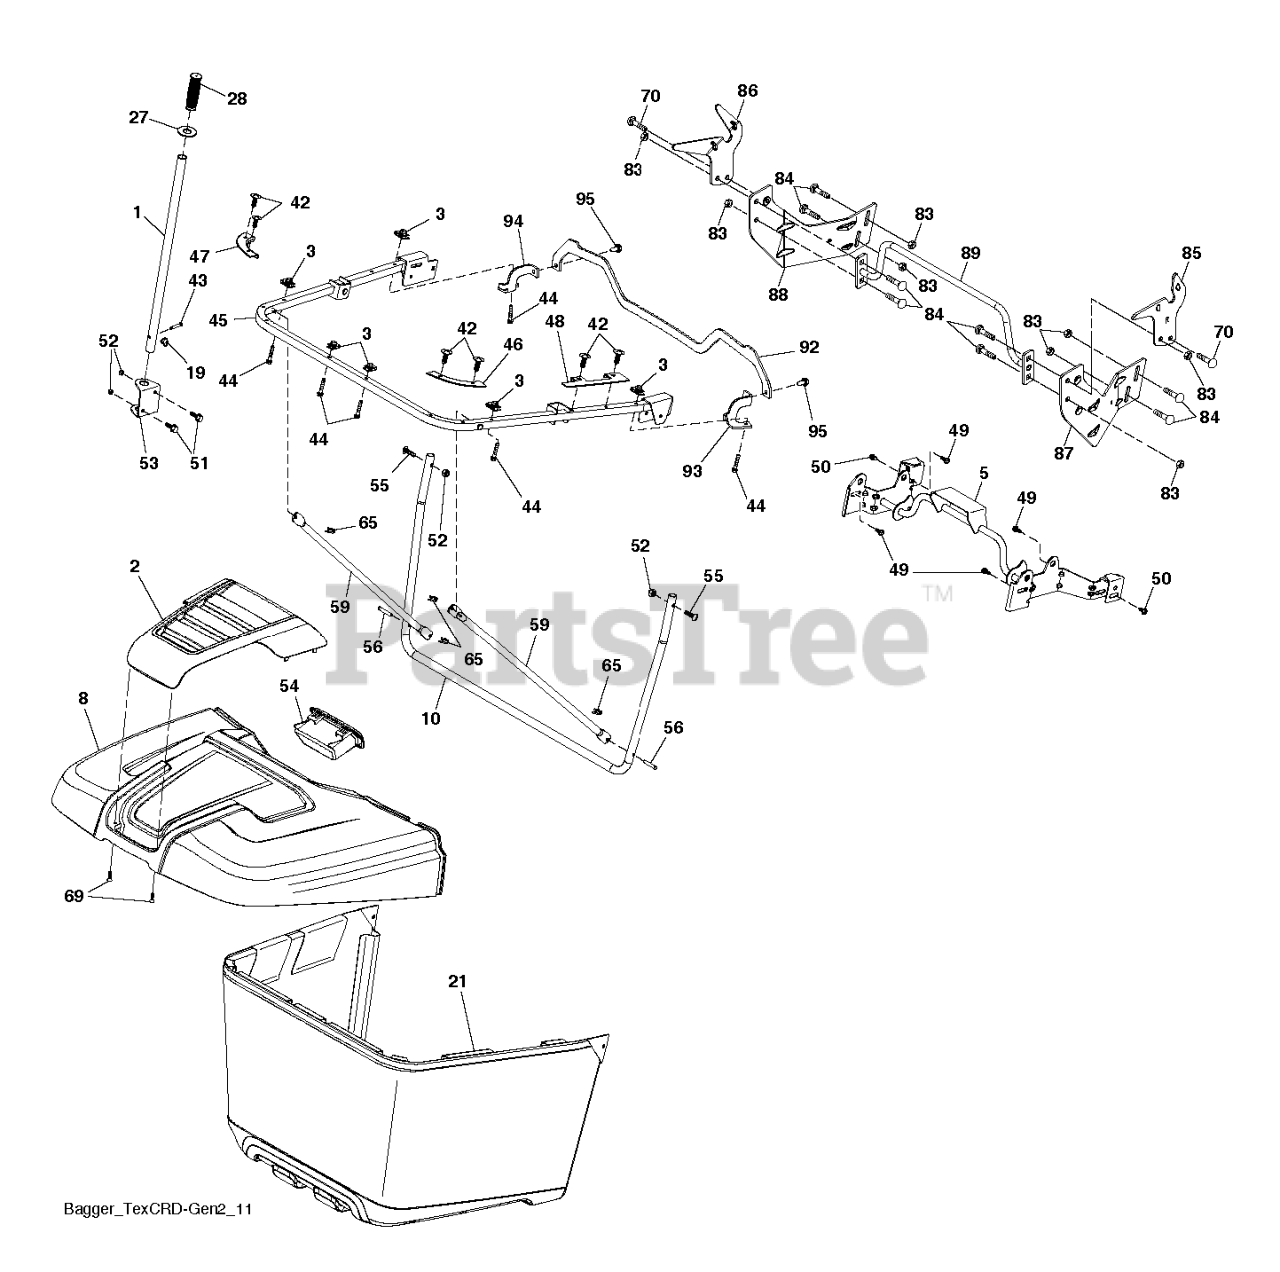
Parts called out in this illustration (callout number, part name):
1	SERVICE KIT TUBE TUBE.HANDLE.B
2	APPLIQUE BAGGER
3	1/4-20 U NUT
5	TCRD.II.UPR.PIVOT TUBE.WLDMT
8	BAGGER.TOP
10	BAGGER.FRAME.LOW.UTUBE.TEX.CRD
19	PIN.COTTER.5/16.BOW TI
21	BAGGER.ASM.FABRIC.CRD.GII.HUSQ
27	RUBBER.GROMMET.DUMP.TUBE.CRDII
28	GRIP.HANDLE.BLACK
42	CHRISTMAS.TREE.CLIP
43	RIVET,DRILLED
45	TCRD.-GEN2.UPPR.U.FRAME.WLDMT
46	LH.BGGR.CRNER.CLOSE-OUT.TEXCRD
47	LH.BAG.CRNER.CLOSE-OUT.TEXCRD
48	TOP.BGGR.SIDE.CLOSE-OUT.TCRDII
49	BOLT, SHOULDER 5/16-18
50	BOLT.5/16-18UNCX3/4 W/SEMS.BLK
51	BOLT.CARR.SQNK.5/16-18UNC.X3/4
53	BRACKET.DUMP.HANDLE.TEX.CRD.G2
54	BAGGER TOP.FRONT.HANDLE
56	PIN.CLEVIS.183
59	BAGGER SPRD.TUBE.TEX.CRD.GEN2
65	RETAINER M
69	SCREW,#8.FLAT.HEAD.DRILL.TIP
70	SCREW, 3/8-16X3/4
85	BRACKET.RH.PIVOT.MAN.DUMP.BLAC
86	BRACKET.LH.PIVOT.MAN.DUMP.BLAC
87	BRACKET.RH.MID.SUP.BAG.TEX.CRD
88	BRACKET.LH.MID.SUP.BAG.TEX.CRD
89	TUBE.WELD.OFSET.STRUT.BAG.X431
92	BRACKET.PNT.BAGGER.TOP.SUPPORT
93	BRACKET.SUPP.ATTACHMENT.RH.431
93	BRACKET.PNT.RH.SUPPORT.ATTACH
94	BRACKET.PNT.LH.SUPPORT.ATTACH
94	BRCKT.ATTACHMENT.SUPP.LH.X431
95	BOLT.HEX.HD.WASHER.5/16-18X.75
